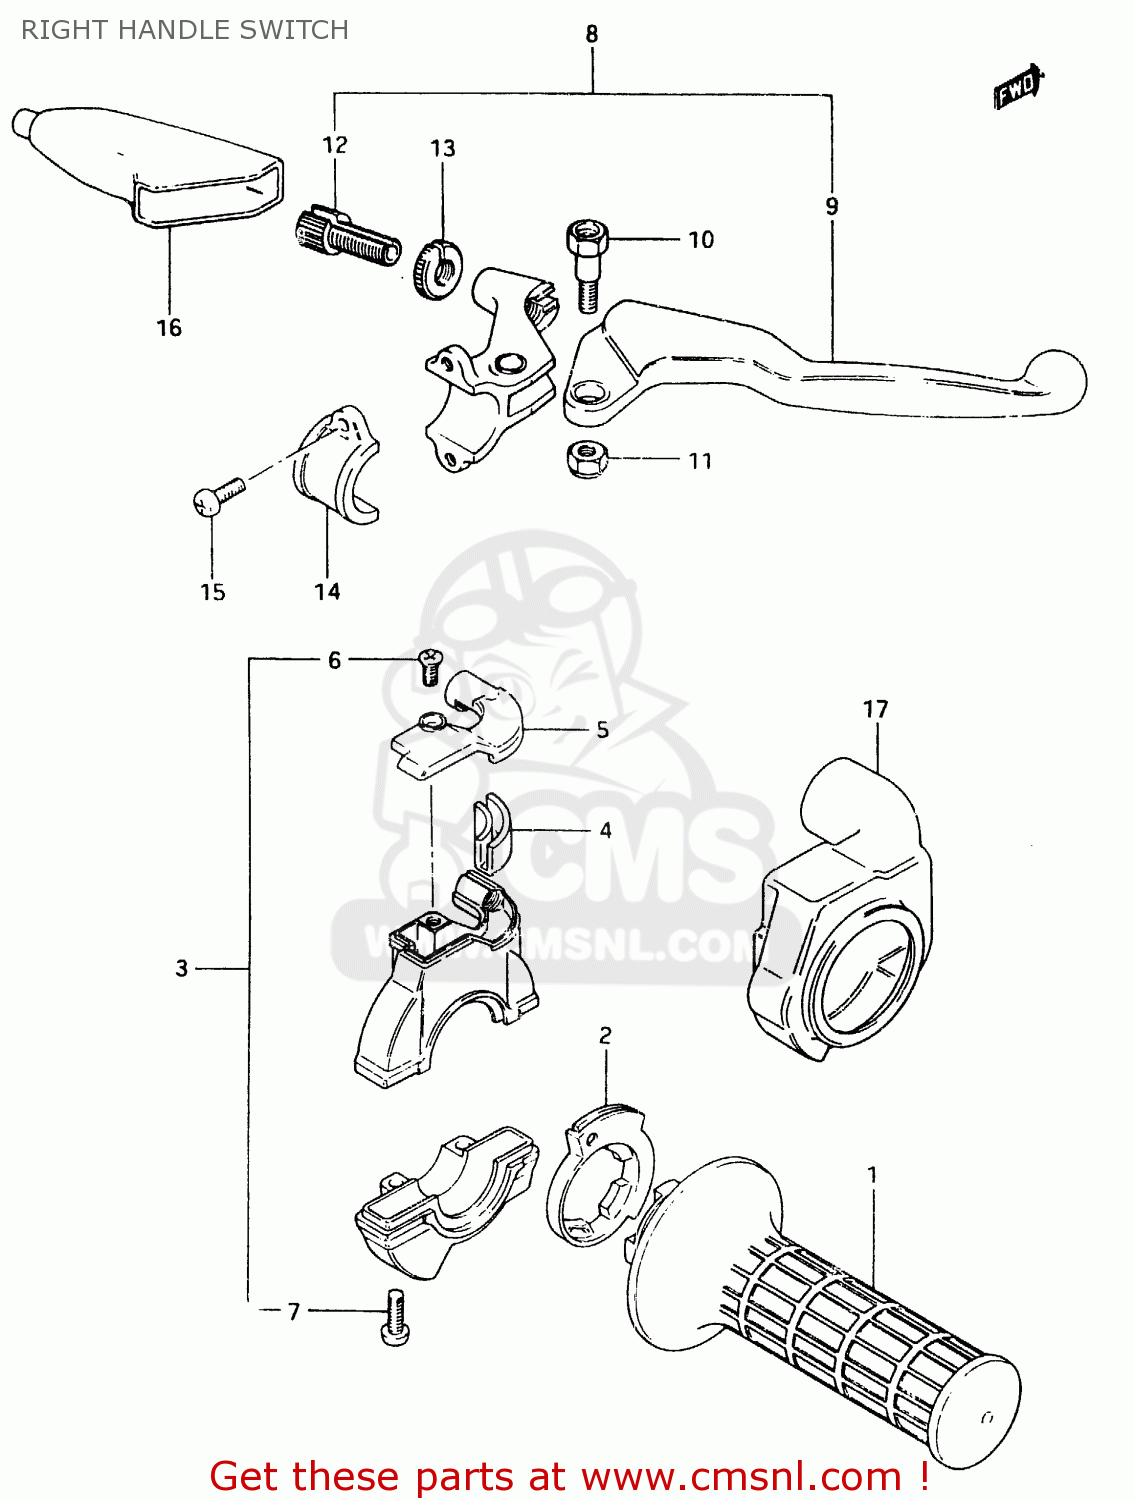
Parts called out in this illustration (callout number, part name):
1	GRIP,THROTTLE
2	ROTOR,THROTTLE GRIP
3	CASE ASSY,THROTTLE
4	GUIDE PIECE,THROTTLE
5	COVER,THROTTLE CASE
6	SCREW
7	SCREW
8	LEVER ASSEMBLY,BRAKE
9	LEVER,BRAKE
10	BOLT,LEVER
11	NUT 6MM
12	ADJUSTER,CABLE
13	NUT,CABLE ADJUSTER
14	BRACKET,CLUTCH LEVER HOLDER
15	SCREW
16	COVER,CLUTCH LEVER
17	COVER,THROTTLE CASE
